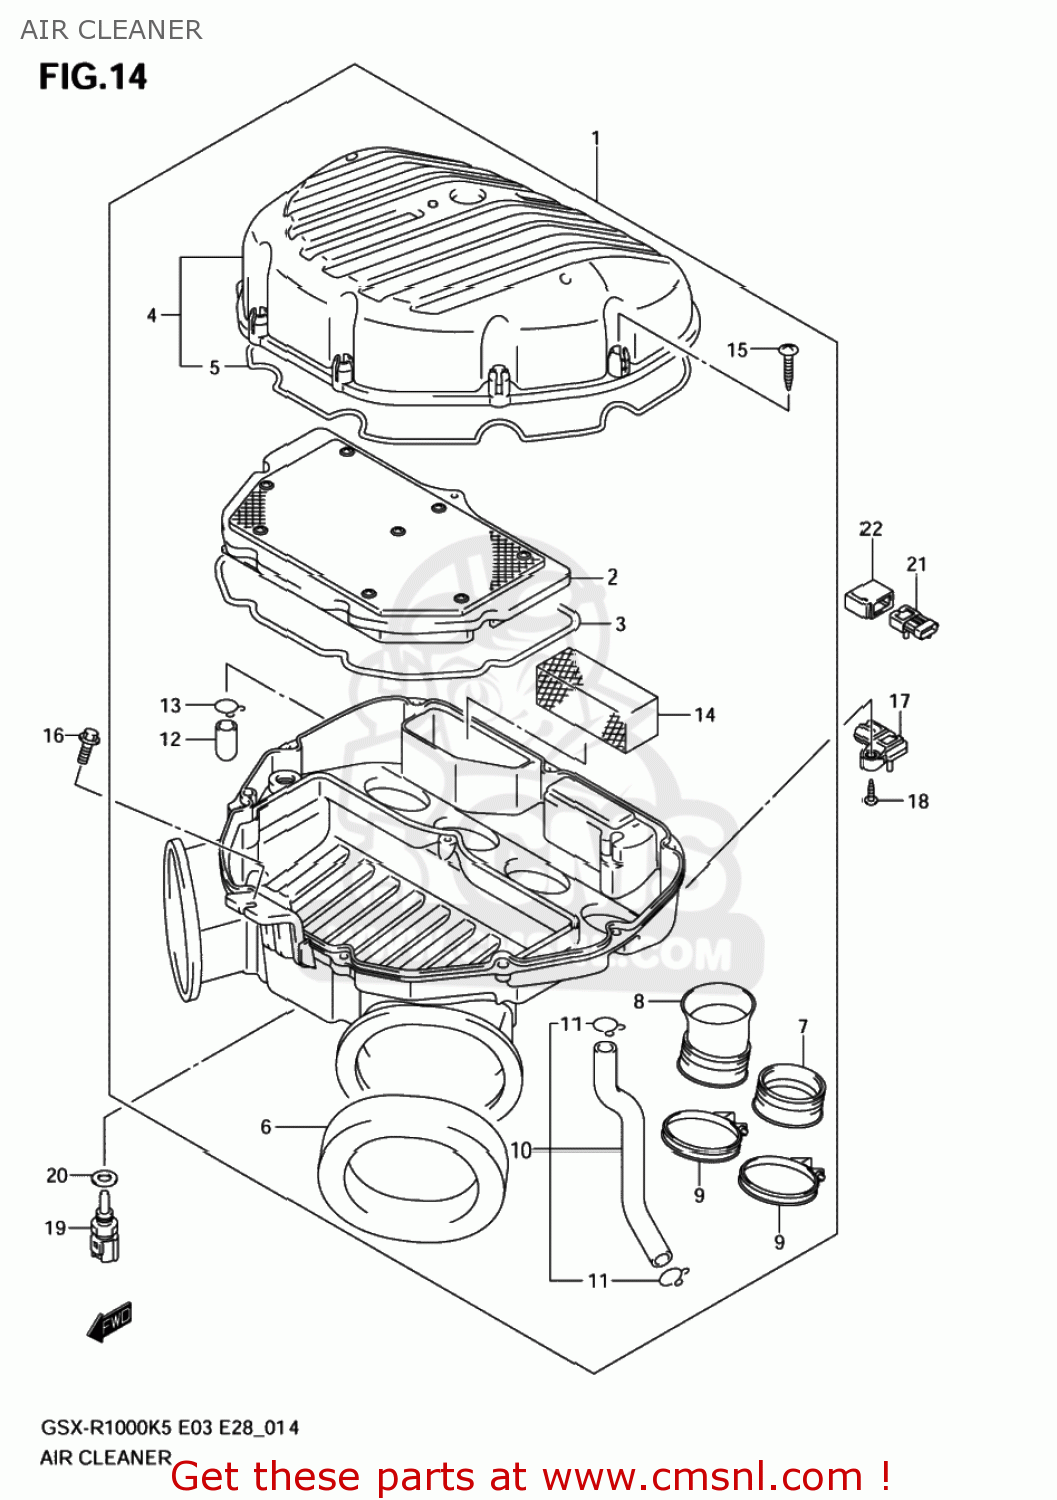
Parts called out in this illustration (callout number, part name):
1	CLEANER ASSY,AIR
2	FILTER ASSY,AIR CLEANER
3	GASKET,CASE (NAS)
4	CAP,AIR CLEANER
5	GASKET,CAP (NAS)
6	CUSHION,DUCT
7	TUBE,OUTLET A
8	TUBE,OUTLET B
9	CLAMP
10	TUBE,BREATHER
11	CLIP
12	PLUG
13	CLIP
14	FILTER,BREATHER
15	SCREW
16	BOLT(6X16)
17	SENSOR,BOOST
18	SCREW
19	SENSOR,WATER TEMP
20	GASKET(12X17X1) (NAS)
21	SENSOR,AIR PRE
22	COVER
